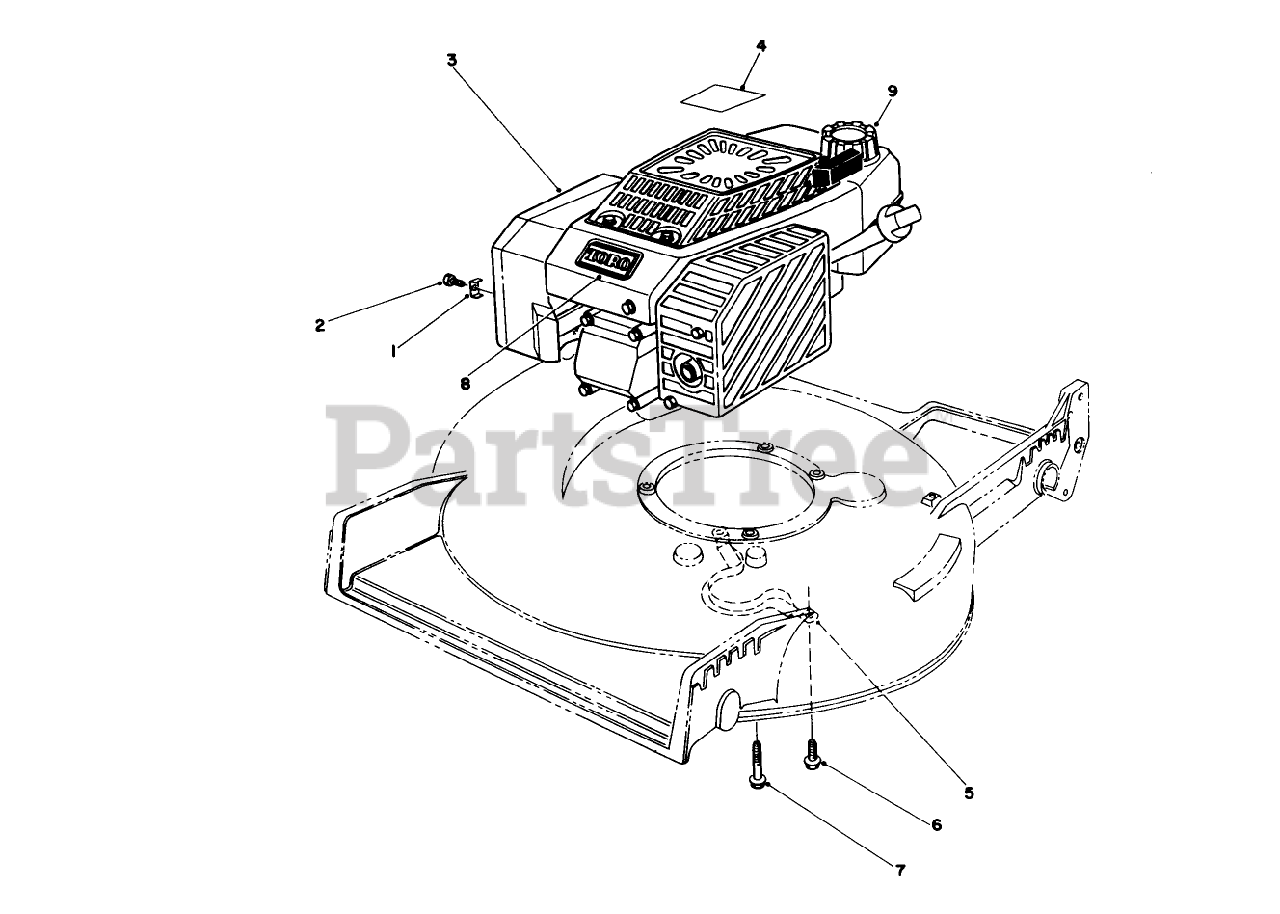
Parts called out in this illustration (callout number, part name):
1	CLAMP-CASING
2	Screw
3	Engine (Incl. Ref. #4, 8, & 9)
4	DECAL - ENGINE
5	Guide-Belt
6	SCREW-HWHTF
7	SCREW-HWH
8	TORO LOGO PLATE
9	GAS CAP ASM
